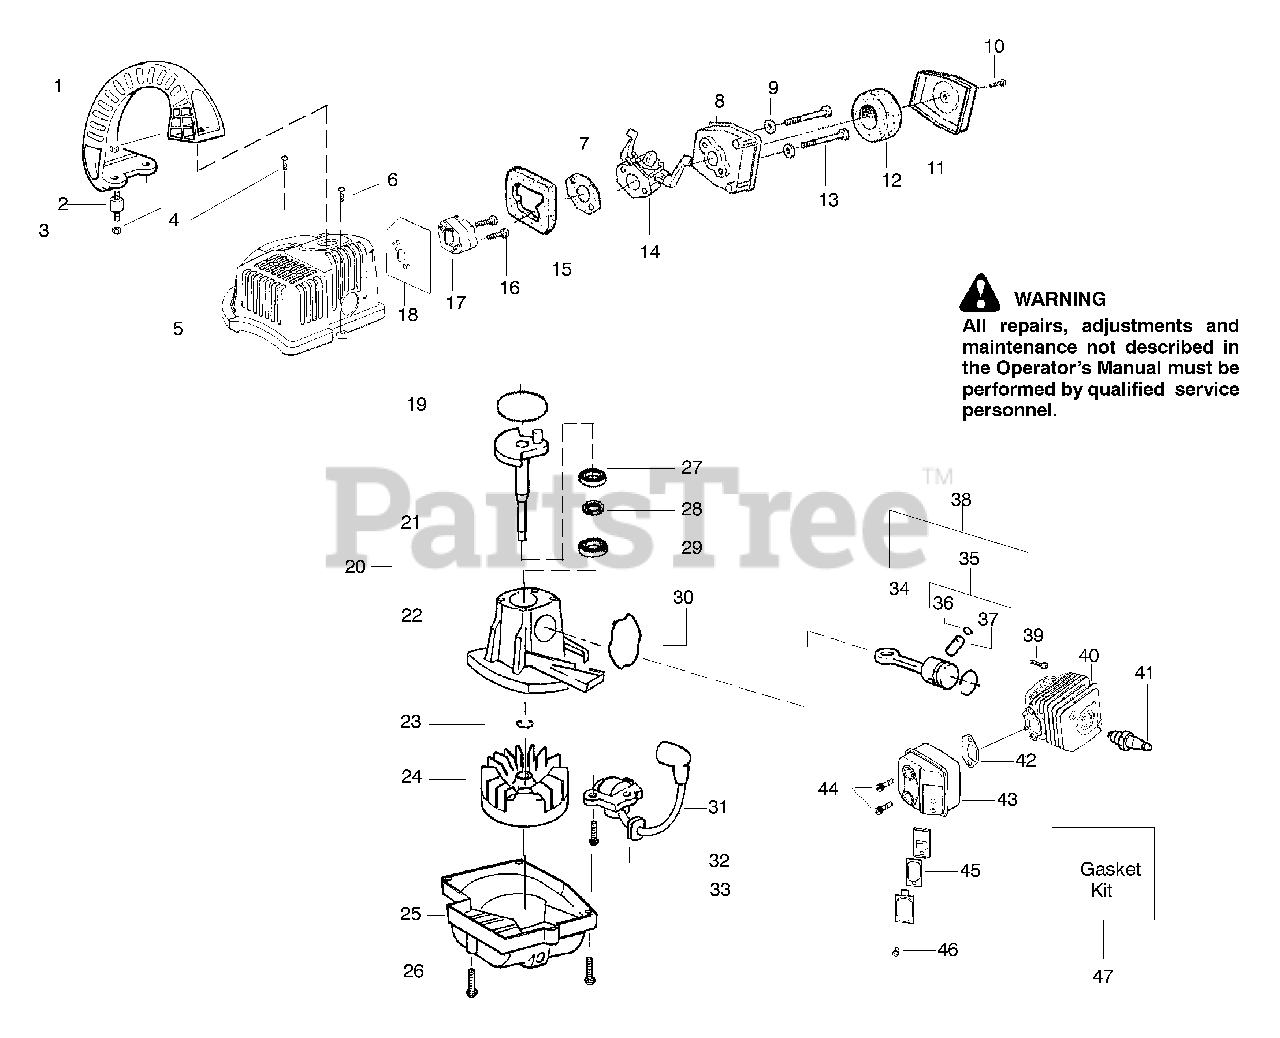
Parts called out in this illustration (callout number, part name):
2	Isolator-Handle
4	Screw
7	Gasket-Carb. (Kit)
9	Washer
11	Cover-Air Box
12	Foam-Air Filter
14	Kit-Carburetor Ass'y. (C1U-W12A)
15	Foam-Air Dam
17	Adaptor-Carb.
18	Gasket-Cyl/Carb. Adaptor (Kit)
19	O-ring-C'case/Shroud (Kit)
20	Assy.-C'case & C'shaft
21	Assy.-Crankshaft
22	Assy.-Crankcase
23	Retainer Ring (C'shaft)
24	Assy.-Flywheel
25	Fan Housing
26	Screw
27	Inner Bearing
28	Seal-Crankcase
29	Bearing-Outer
30	Seal-Cylinder (Kit)
31	Ignition Module
32	Grommet-Ign. Module
34	Kit-Connecting Rod Assy.
35	Kit-Piston
36	Wrist Pin Retainer
37	Piston Ring
38	Kit-Piston/Rod Assy.
40	Cylinder
41	Spark Plug (RCJ-6Y)
42	Gasket-Muffler (kit)
43	Kit-Muffler
44	Bolt-Muffler
45	Kit-Spark Aresstor
47	Kit-Gasket
